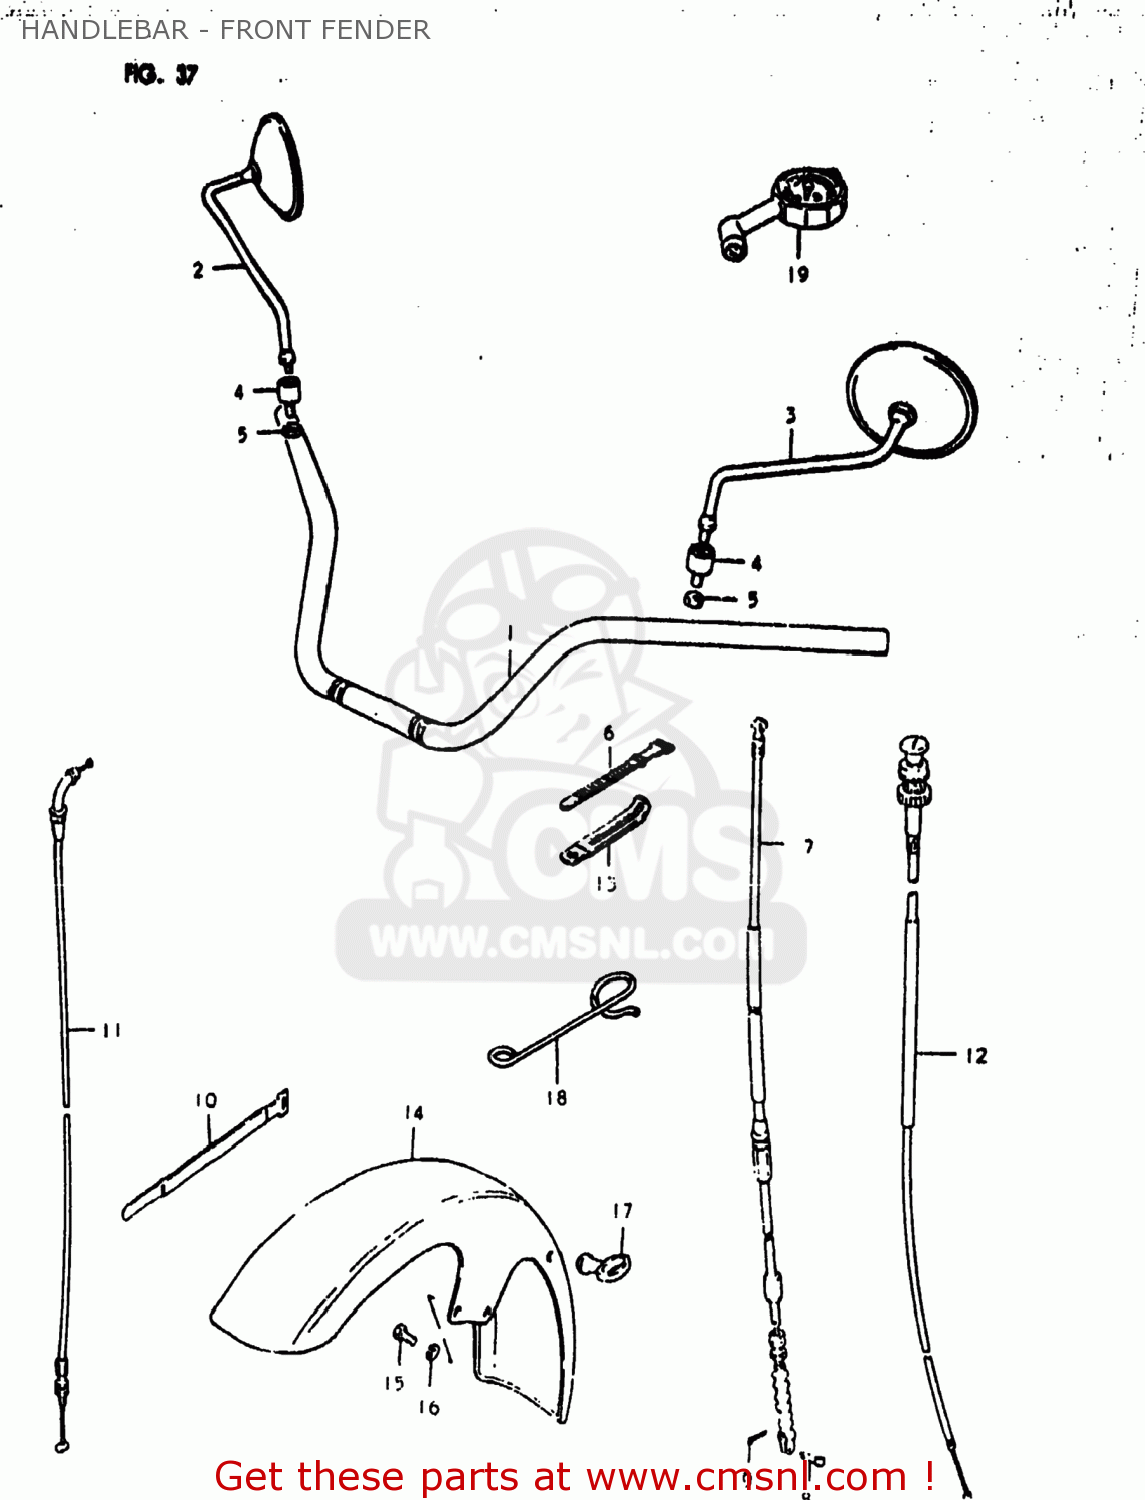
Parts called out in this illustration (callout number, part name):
1	HANDLEBAR
2	MIRROR ASSEMBLY,RIGHT
3	MIRROR ASSEMBLY,LEFT
4	CUSHION,REAR VIEW MIRROR
5	NUT
6	CLAMP(L:120)
7	CABLE ASSY,CLUTCH
8	PIN(L:15)
9	PIN
10	CLAMP
11	CABLE ASSEMBLY,THROTTLE
12	CABLE ASSEMBLY,STARTER
13	CLAMP
14	FENDER,FR
15	BOLT
16	LOCK WASHER
17	GUIDE,CABLE
18	GUIDE,CABLE
19	GAUGE ASSY,AIR PRESSURE
